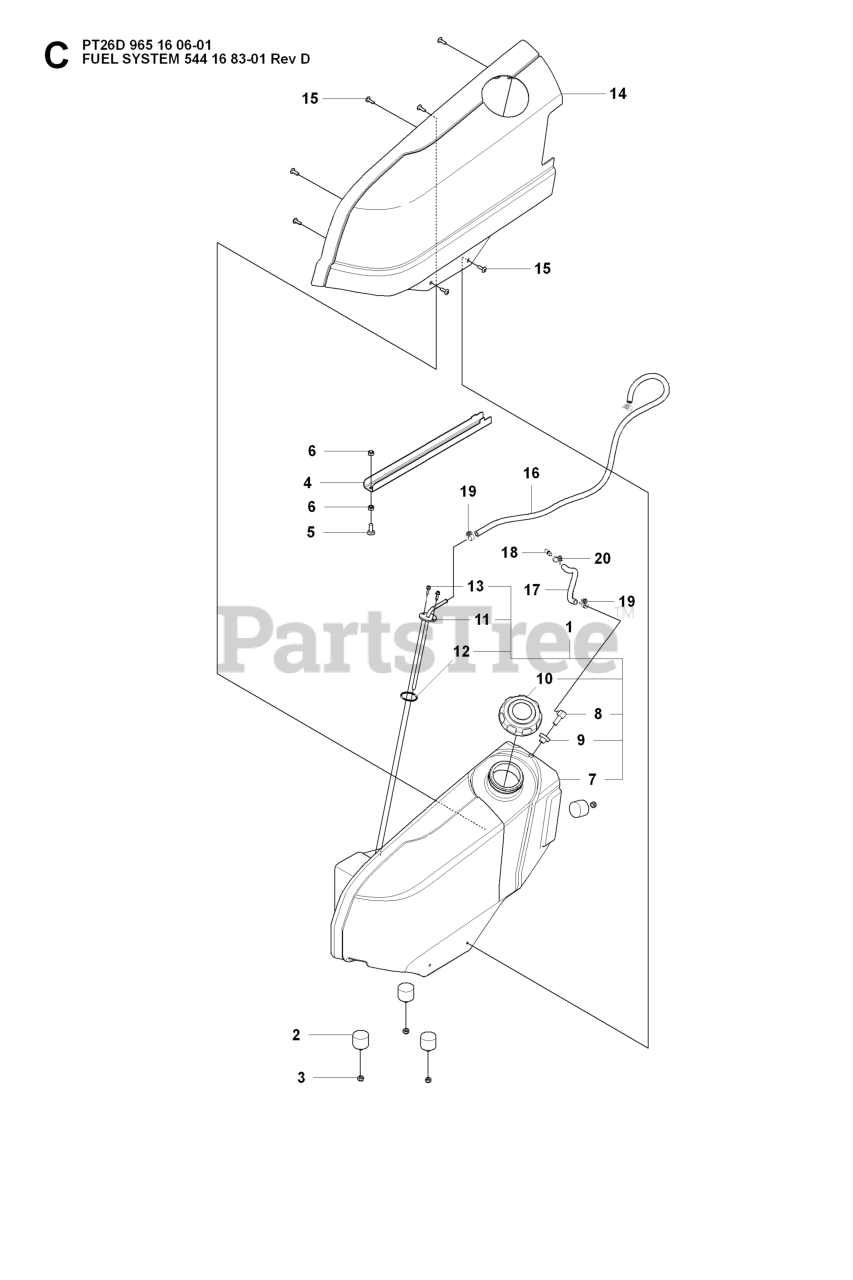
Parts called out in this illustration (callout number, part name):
1	FUEL TANK ASSY
2	ANTIVIBRATION ELEMENT
3	LOCKNUT M8
6	LOCKNUT M8
9	RUBBER GROMMET
10	TANK CAP - DIESEL
11	CONNECTION FUEL TANK
14	TANK COVER FUEL TANK
19	RP HOSE CLAMP FUEL HOSE
20	HOSE CLAMP FUEL HOSE
